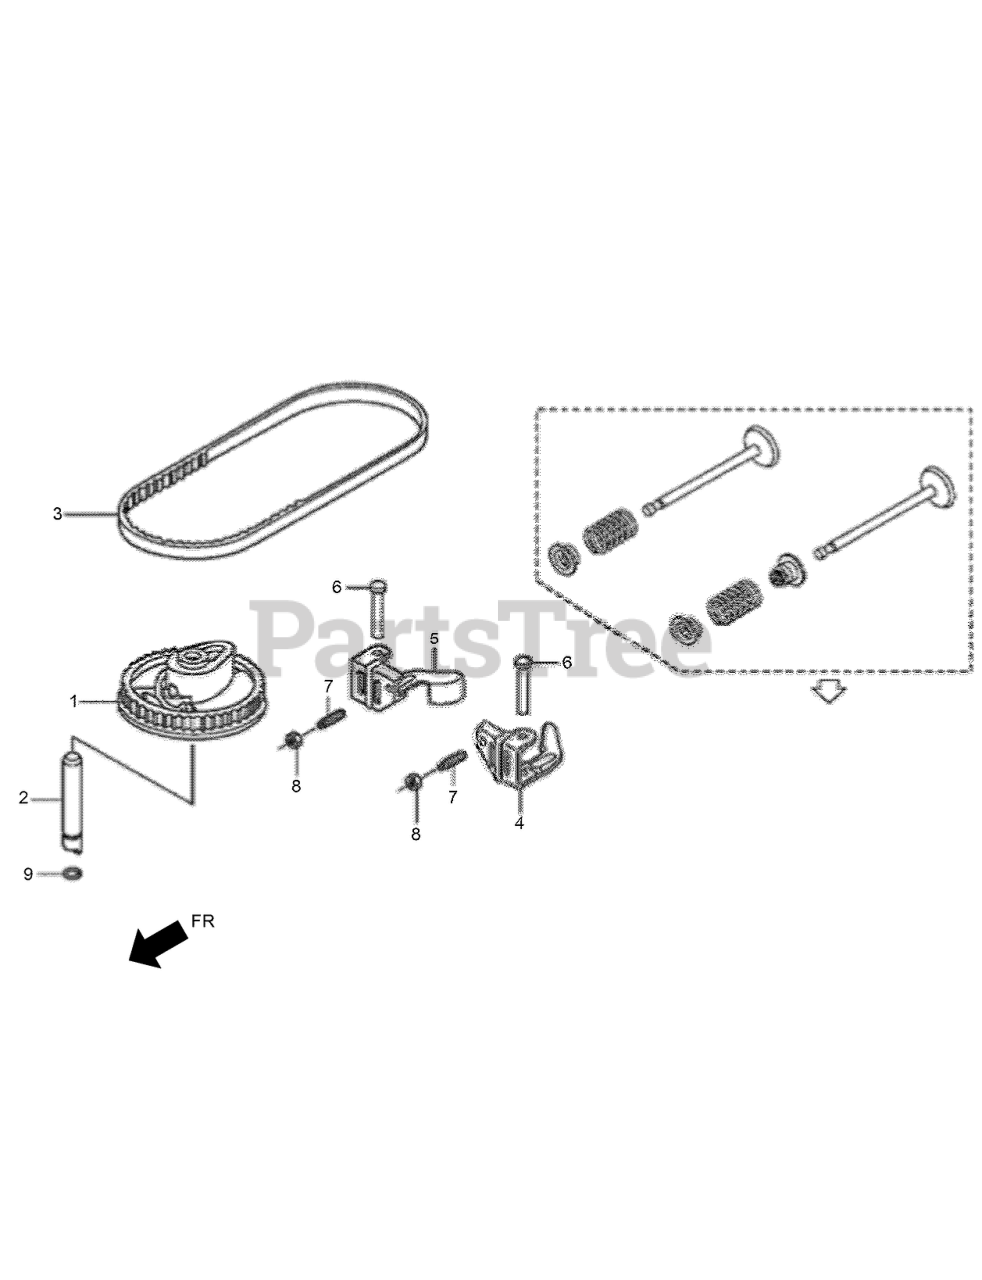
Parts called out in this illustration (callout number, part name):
1	PULLEY-CAMSHAFT
2	SHAFT-CAM PULLEY
3	BELT-TIMING
4	ARM-INTAKE VALVE ROCKER
5	ARM-EXHAUST VALVE ROCKER
6	SHAFT-ROCKER ARM
7	SCREW-TAPPET ADJUSTING
8	NUT-TAPPET ADJUSTING
9	O-RING-6.8X1.9
